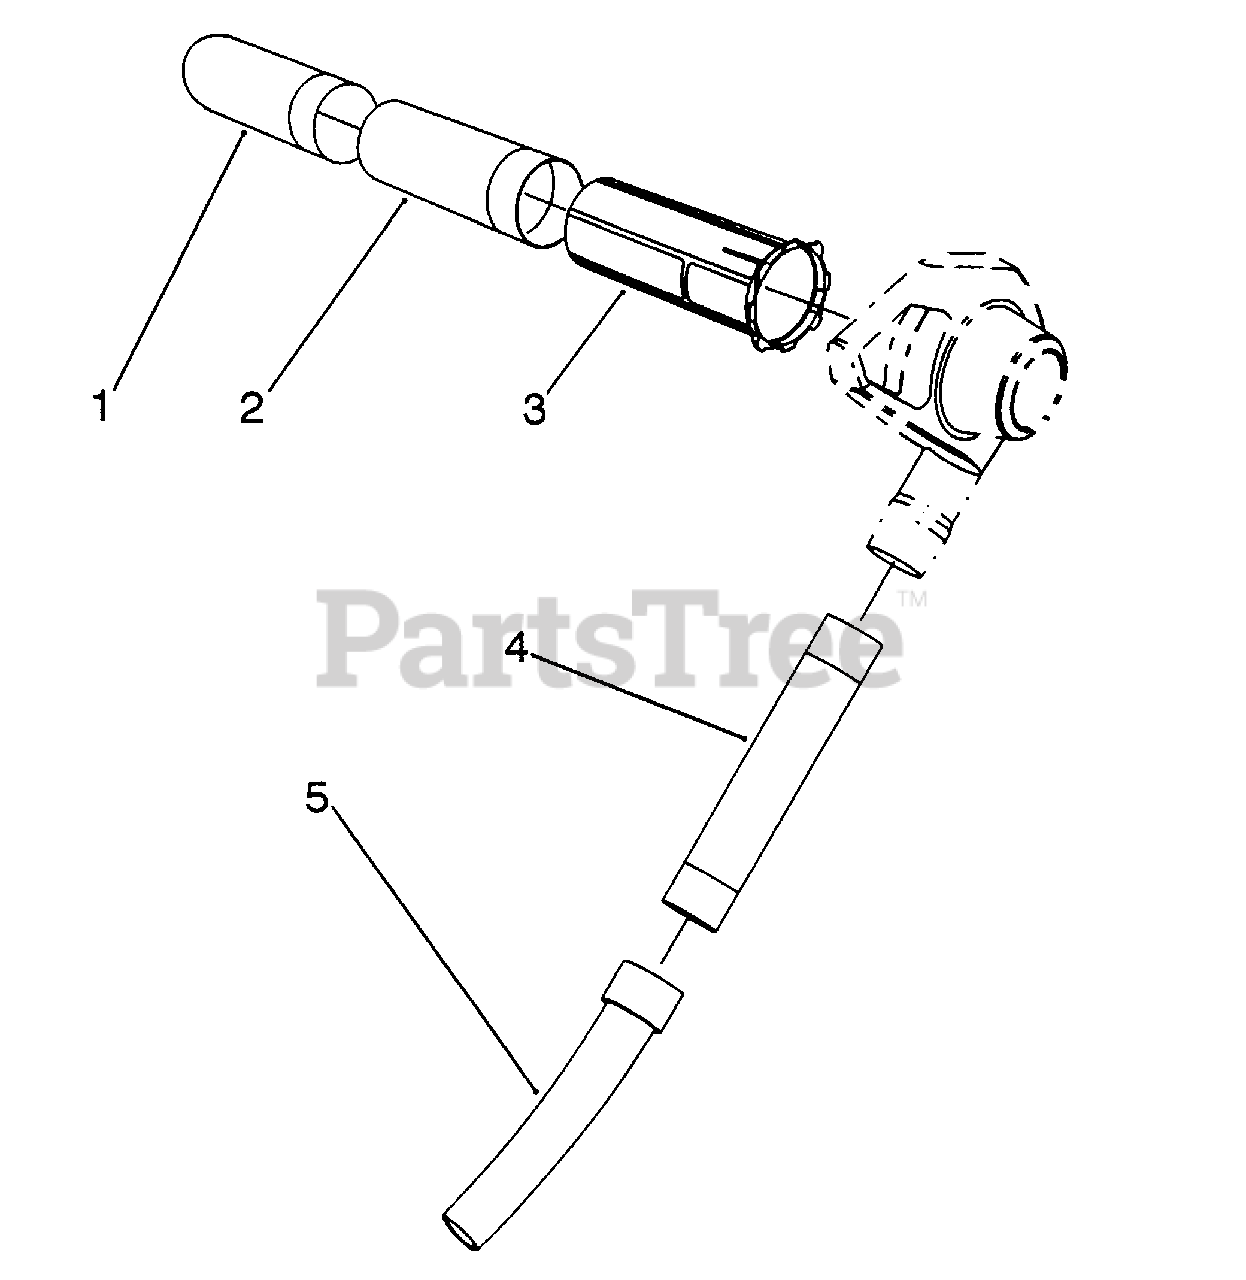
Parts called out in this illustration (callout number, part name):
1	Vac Tube-Lower 73-1460
2	Vac Tube-Middle 73-1450
3	Vac Tube-Upper 73-3990
4	Tube-Blower
